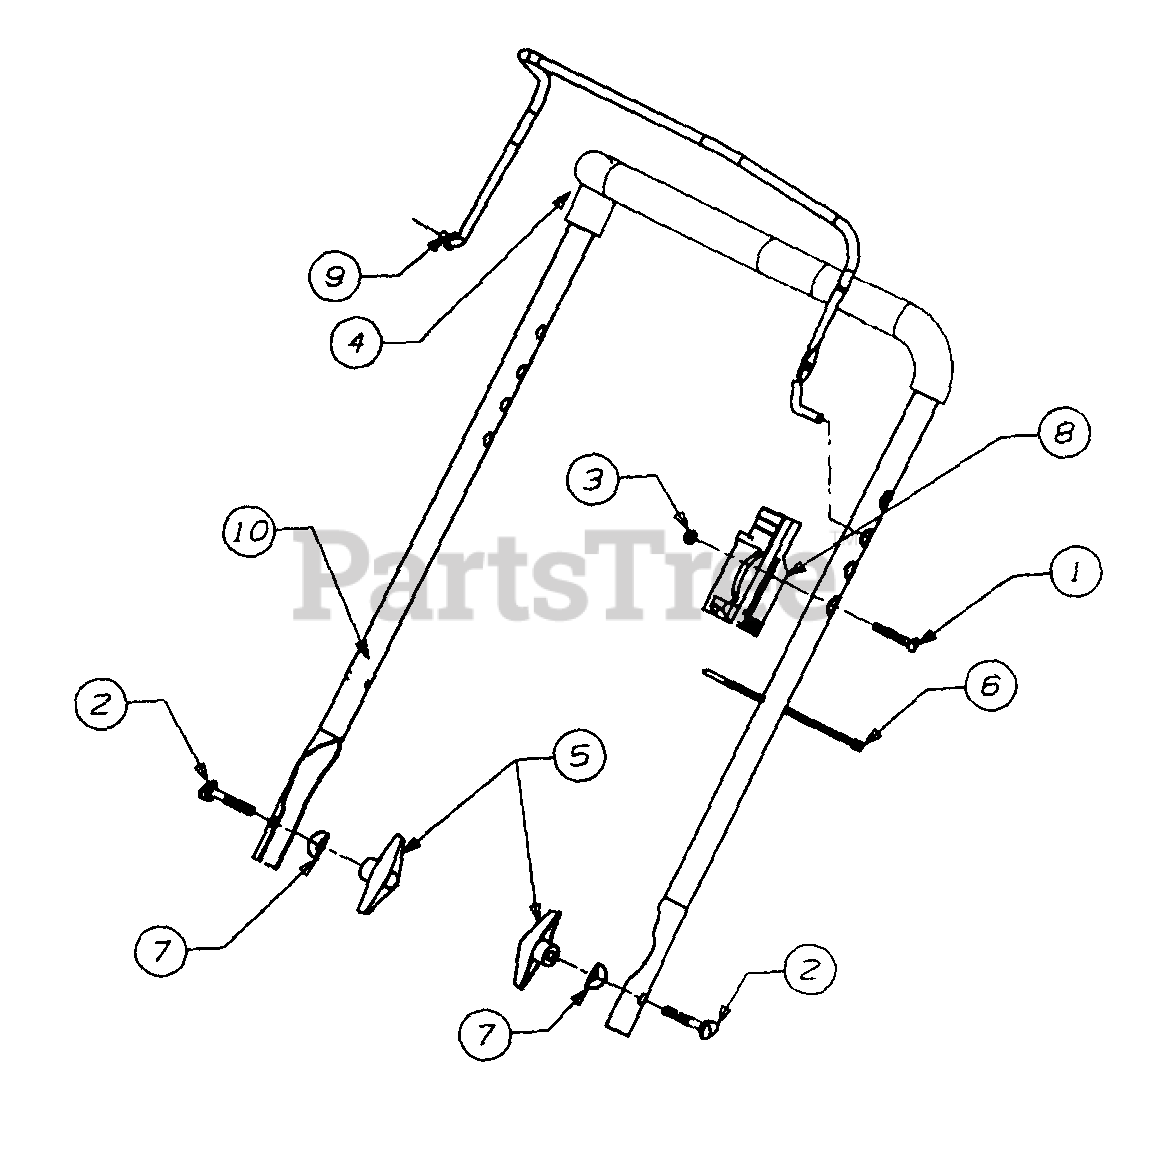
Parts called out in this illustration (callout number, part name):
1	Screw - Oval C-Sink L
2	Bolt - Carriage
3	Nut Insul. Lock
4	Grip Foam
5	Knob Handle
6	Tie Cable
7	Washer Saddle
8	Body - Lever Control
9	Handle Ass'y. Control
